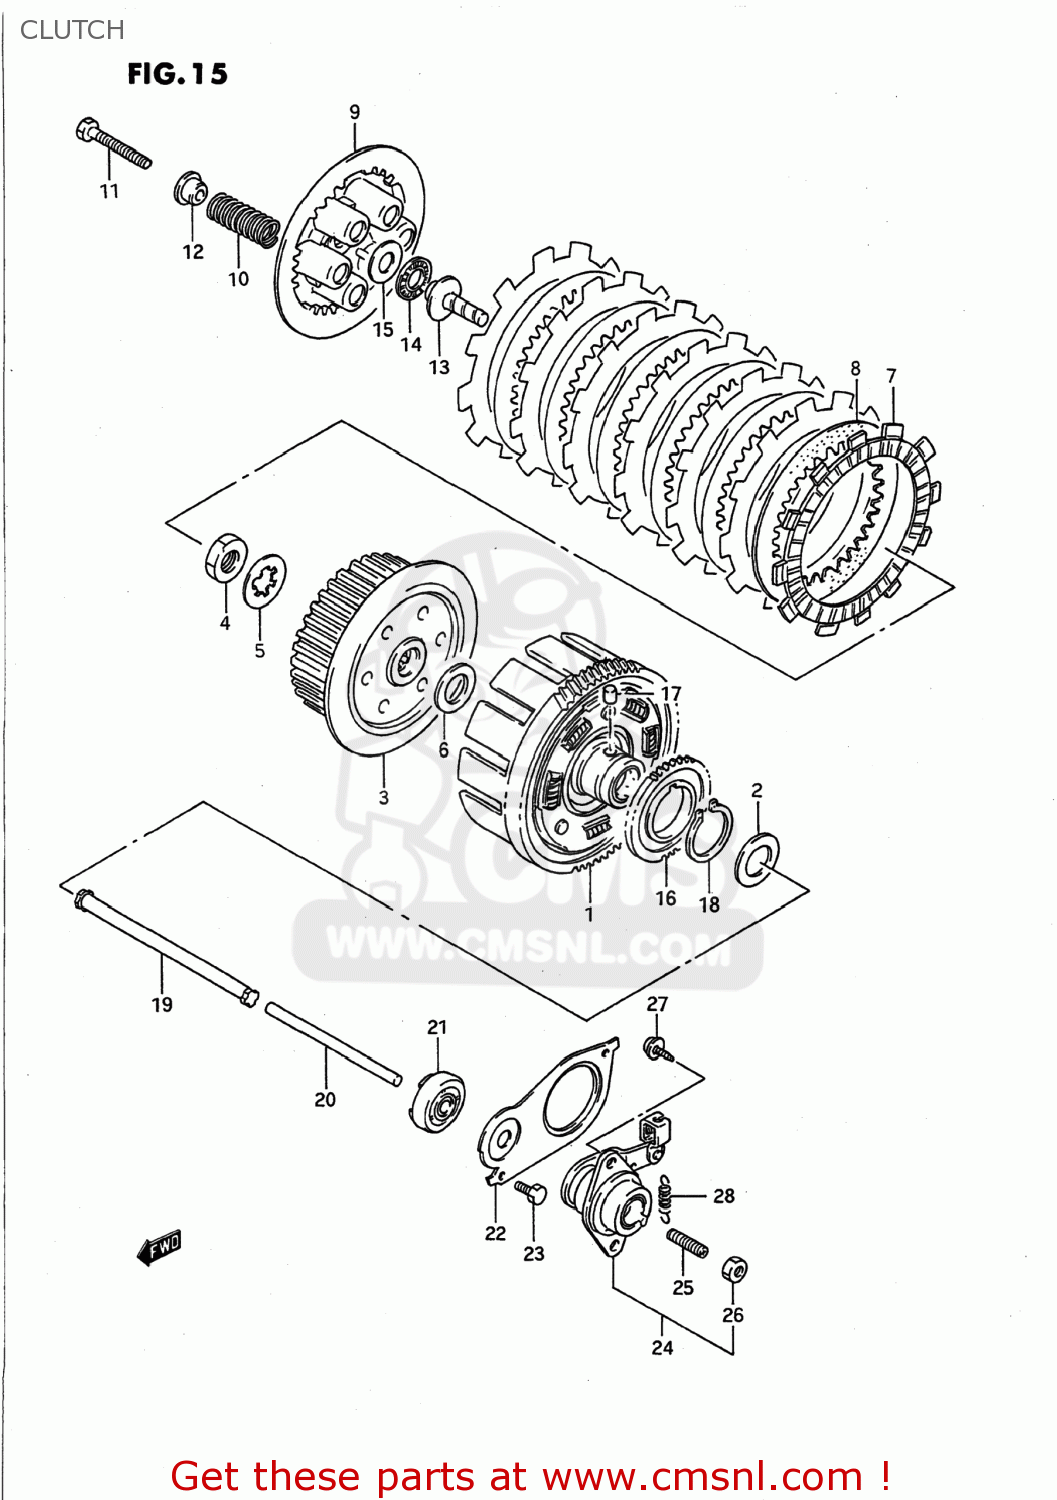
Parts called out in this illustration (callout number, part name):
1	GEAR ASSY,PRI DRIVEN
2	WASHER
3	HUB,CLUTCH SLEEVE
4	NUT (20MM)
5	WASHER,LOCK
6	WASHER(20X44X3)
7	PLATE,CLUTCH DRIVE (NAS)
8	PLATE,CLUTCH DRIVEN (NAS)
9	DISC,CLUTCH PRESSURE
10	SPRING
11	BOLT(6X40)
12	SPACER,CLUTCH SLEEVE HUB
13	PIECE,CLUTCH PUSH
14	BEARING(15X28X2)
15	WASHER
16	GEAR,OIL PUMP DRIVE
17	PIN(6X6)
18	CIRCLIP
19	ROD,PUSH,R
20	ROD,CLUTCH PUSH,L
21	SEAL,OIL(6X34X10)
22	PLATE,CLUTCH PUSH ROD
23	BOLT
24	SCREW ASSY,CLUTCH RELEASE
25	SCREW(6X25)
26	NUT 6MM
27	SCREW
28	SPRING
